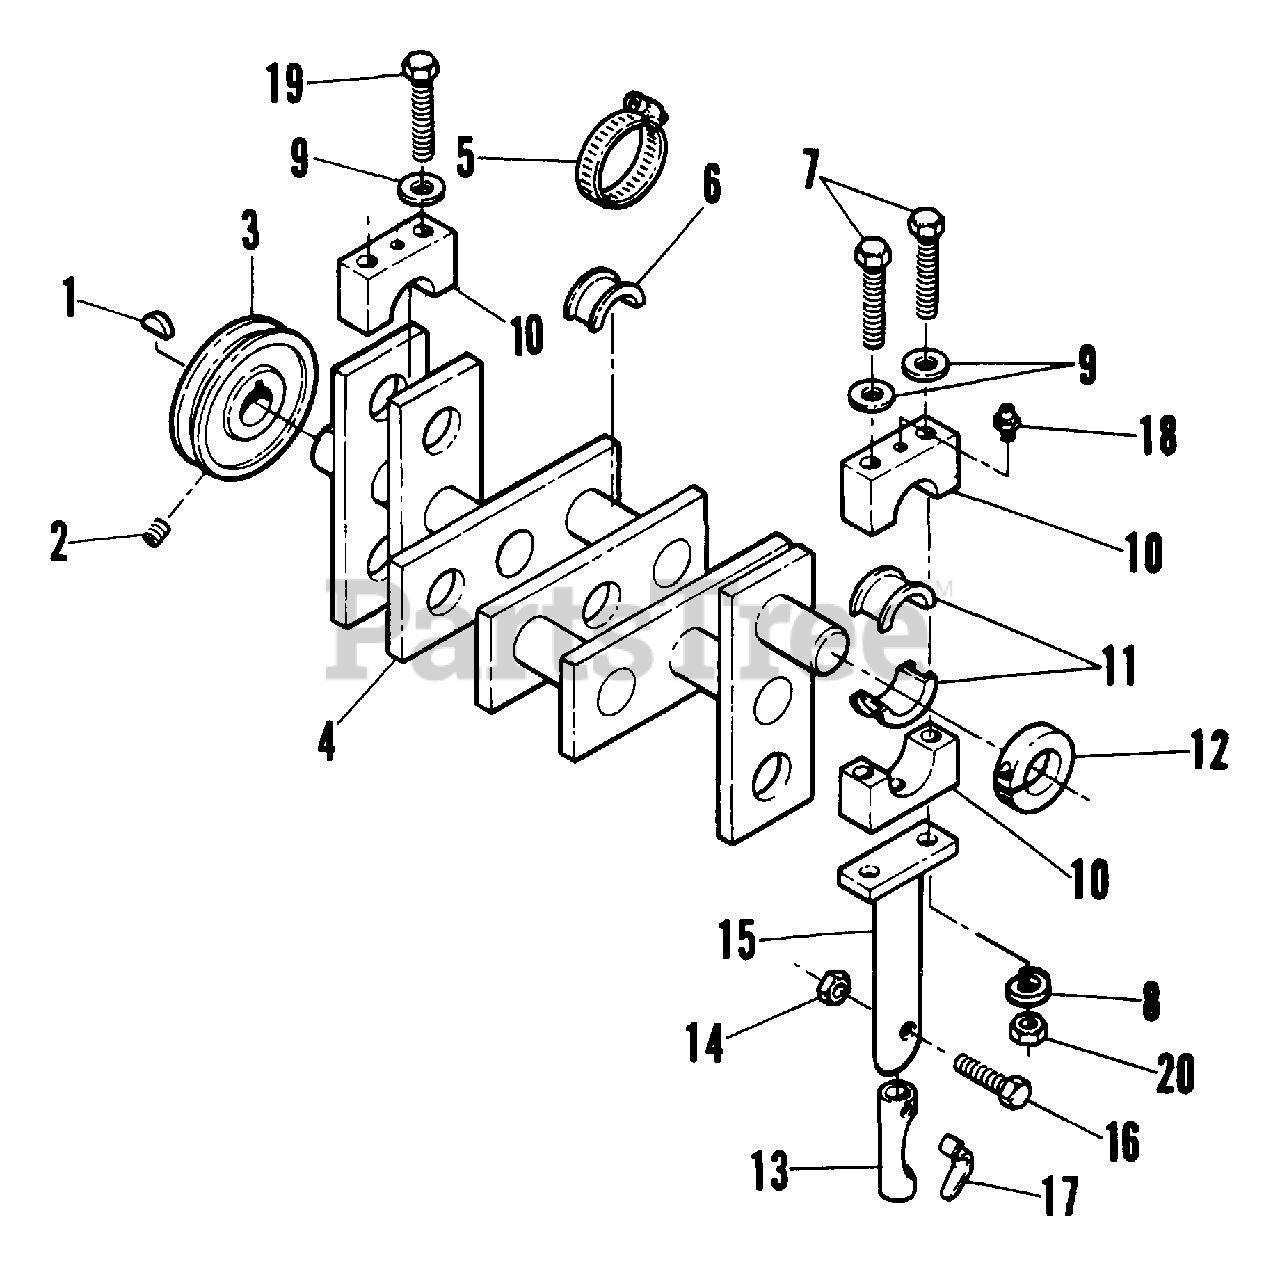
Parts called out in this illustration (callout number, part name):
1	WOODRUFF KEY, #807
2	NYLOC SETSCREW, 5/16 - 18 x 3/8"
3	PULLEY W/SETSCREW
4	CRANKSHAFT
5	HOSE CLAMP
6	SHAFT SPACER
7	TAPBOLT GR. 5, 5/16" - 18 x 3 1/4" Hex. Hd.
8	LOCKWASHER, 5/16"
9	FLAT WASHER, 5/16" Std.
11	BUSHING
12	CLAMP COLLAR
14	NYLOC HEX. NUT, 1/4" - 20
15	CONNECTING ROD
16	CAPSCREW GR. 5, 1/4" - 20 x 1 1/2" Hex. Hd.
17	PLUG EJECTOR
18	ZERK
19	CAPSCREW GR. 5, 5/16" - 18 x 4 1/2" Hex. Hd.
20	NYLOC HEX. NUT, 5/16" - 18
